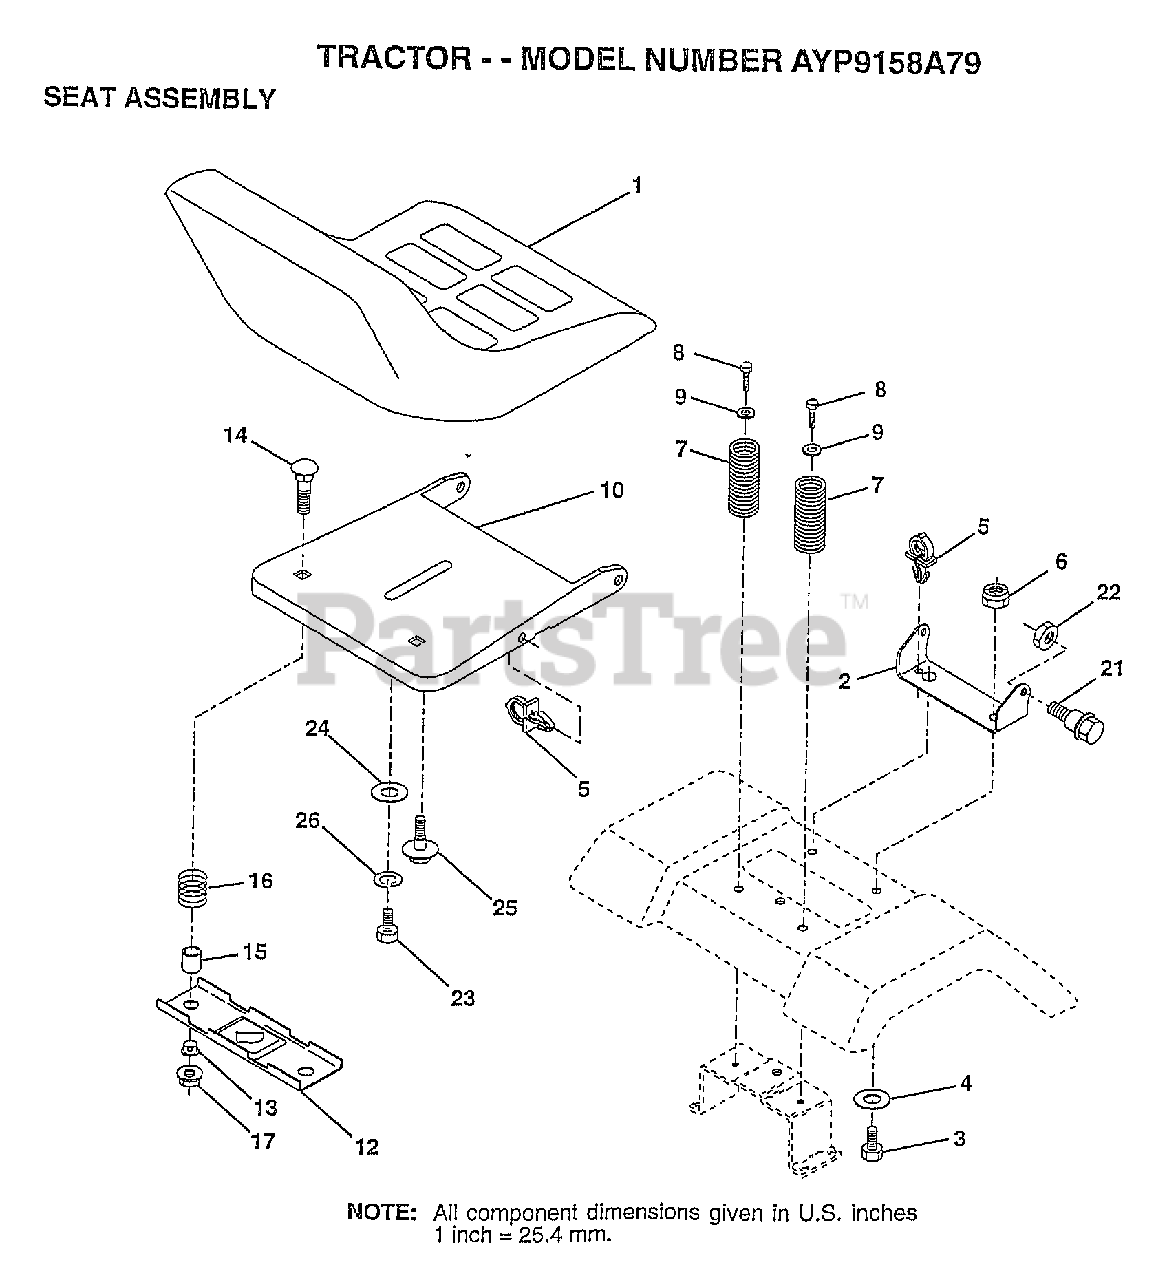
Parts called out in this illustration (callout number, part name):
1	SEAT.2400/1416.BK
2	BRACKET PVT SEAT
3	BOLT
4	WASHER PM
5	CLIP.PUSH-IN.HING
6	NUT
7	SPRING COMPRESSIO
8	SCREW GTV
9	WASHER
10	PAN-SEAT
12	BRKT SWITCH
13	BUSHING
15	SPLIT SPACER
16	SPRING
21	"BOLT,SHOULDER"
22	NUT
23	BOLT
24	WASHER
25	"BOLT,SHOULDER"
26	LOCKWASHER
